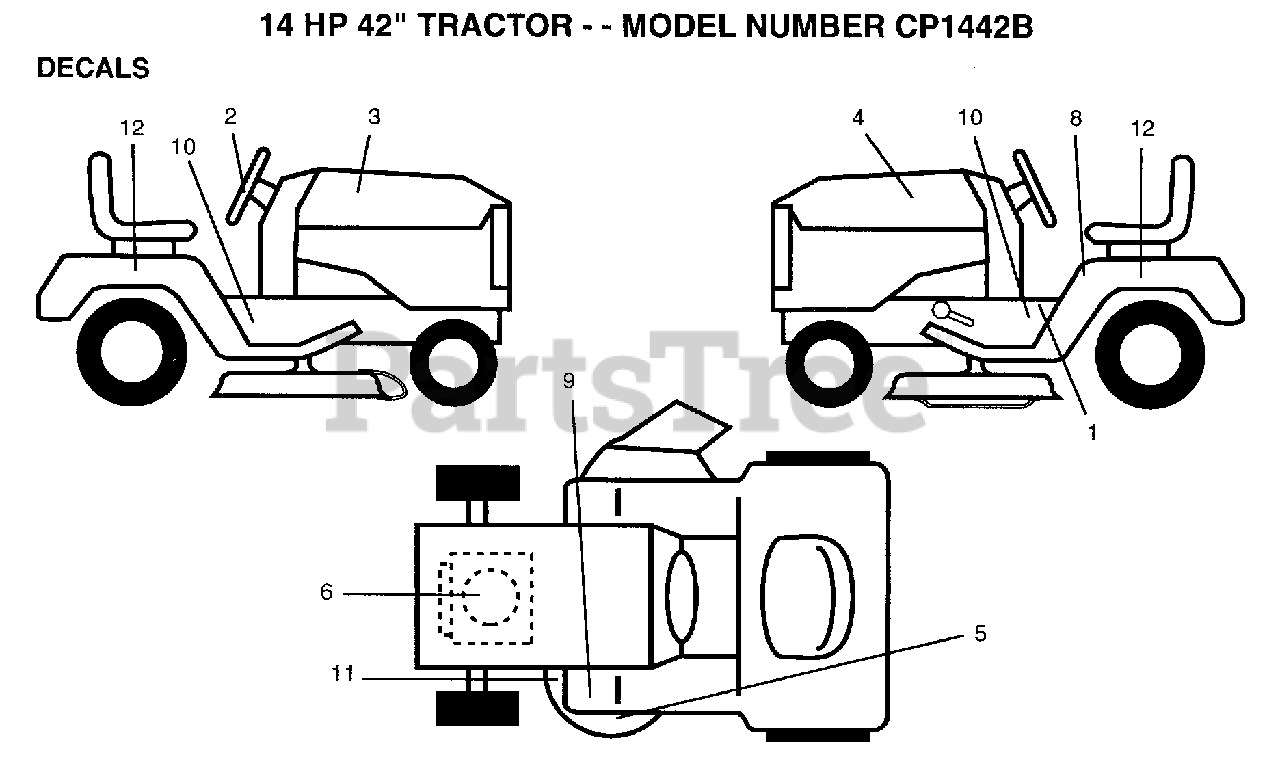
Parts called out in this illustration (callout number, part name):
3	DECAL.HD.RH.CNTPK
4	DECAL.HD.LH.CNTPK
6	DECAL.ENG.272750
8	DECAL
10	CHASSIS DECAL
11	DECAL.V.BELT
12	DECAL.FEND.QUICK.
